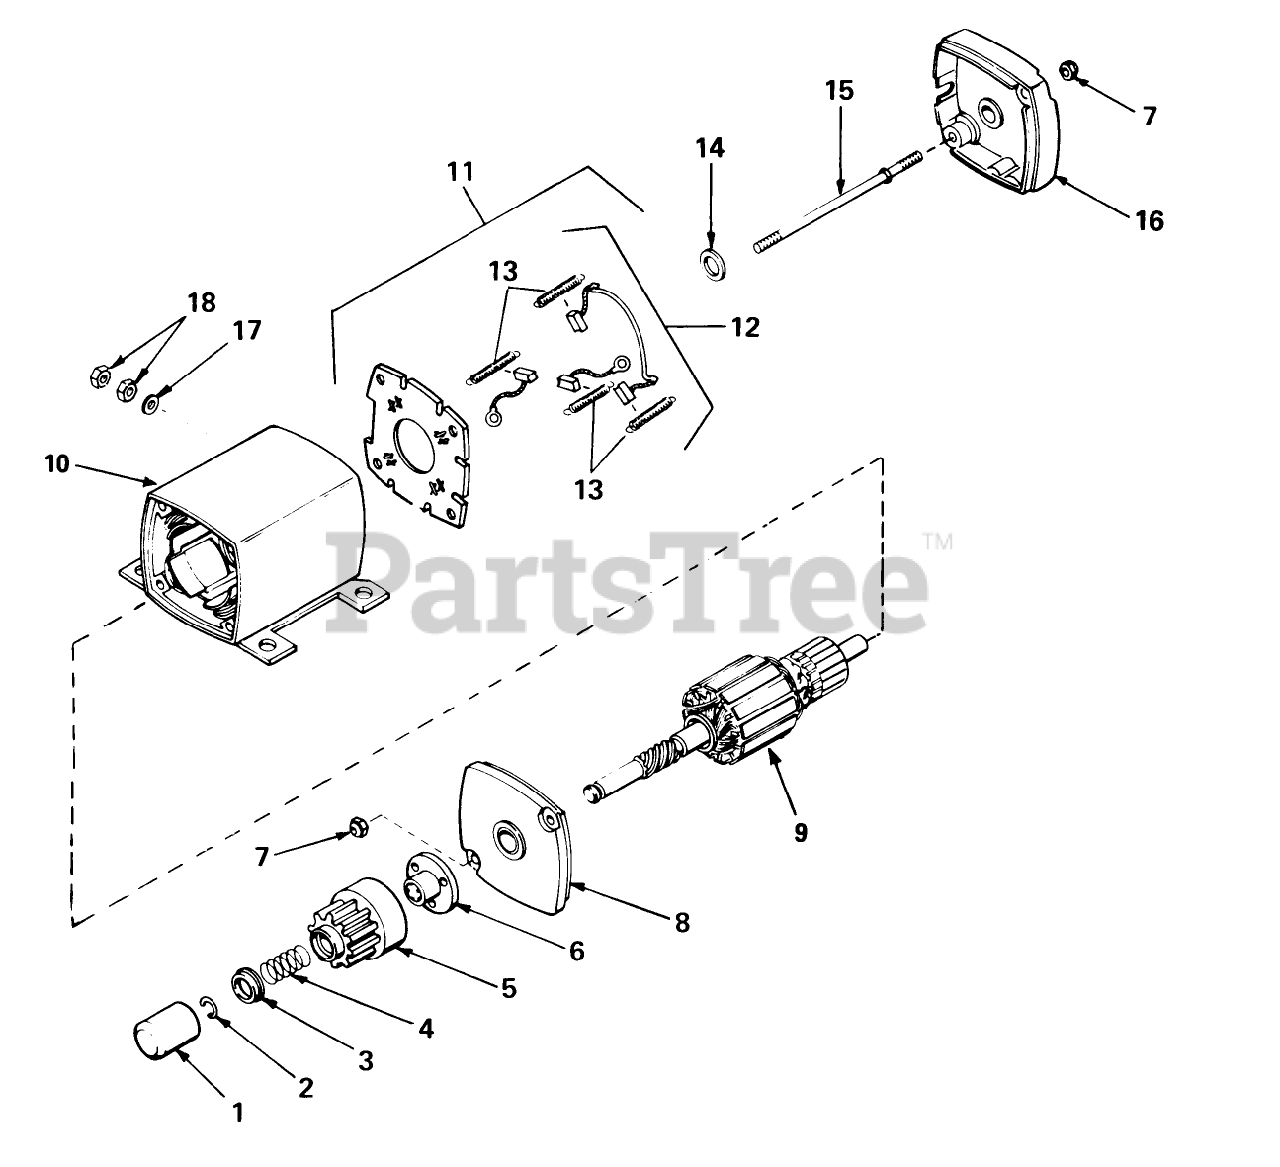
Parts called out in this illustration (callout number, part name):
1	Cover-Dust
2	Ring-Retainer
3	Retainer-Spring
4	Spring-Anti Drift
5	Gear
6	Nut-Engaging
7	Nut-Lock
8	Cap Assy., Drive End
9	Armature
10	Housing Assembly (Incl. Ref. #11)
11	Card Assy., Brush (Incl. No. 12)
12	Brush Spring Kit (Incl. 4 pcs. of #13)
13	1545D SUP TO W/3256
14	Washer-Thrust
15	Bolt
16	2035A67 WIZARD W/34
17	Washer
18	Nut-Hex
19	Washer-Thrust
